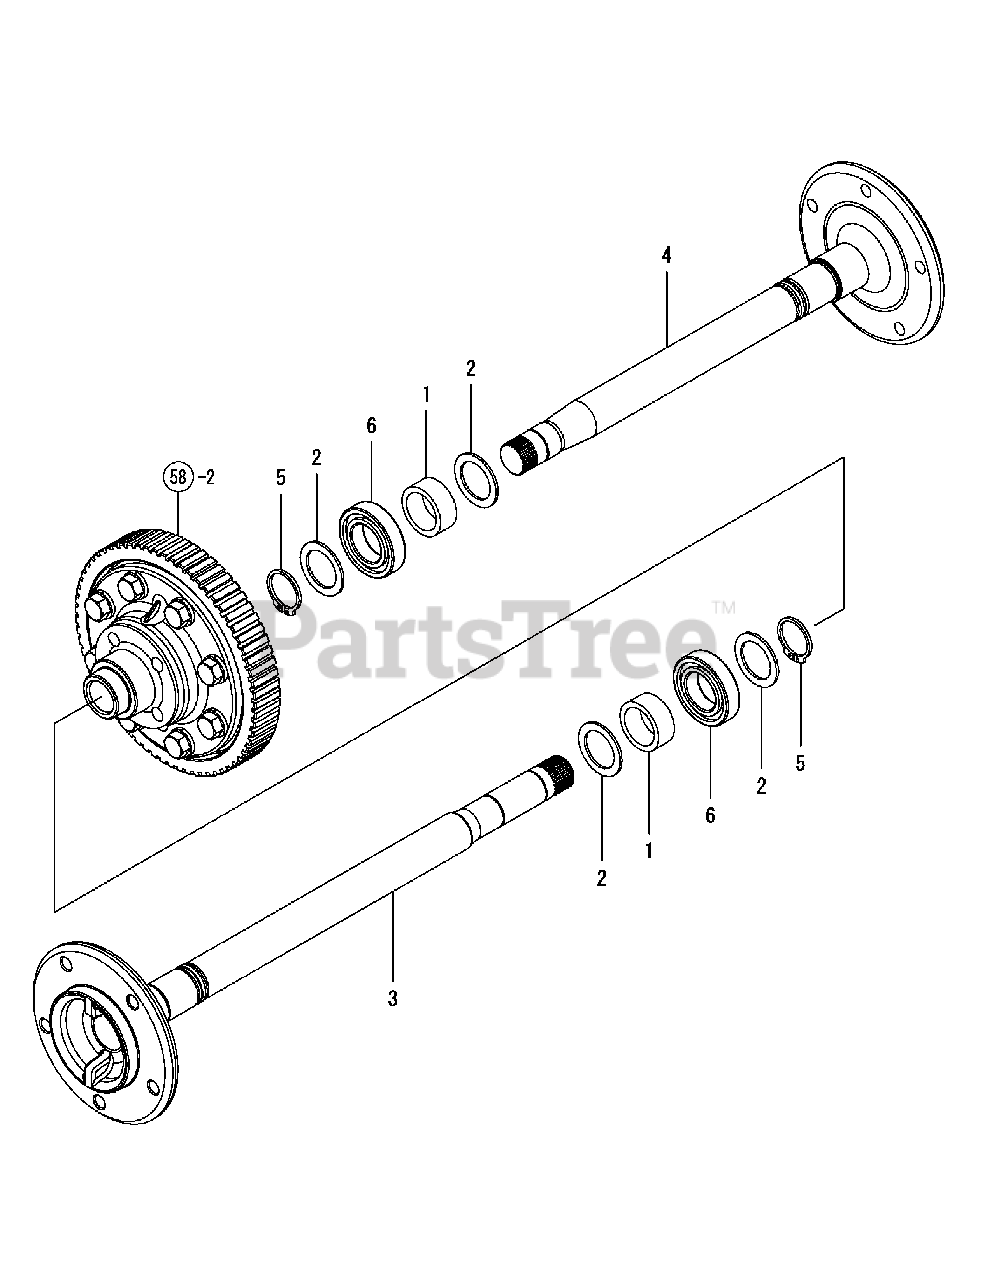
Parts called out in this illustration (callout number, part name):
1	SLEEVE 30X39X16
2	COLLAR 30X42X2
3	SHAFT, REAR AXLE L
4	SHAFT, REAR AXLE R
